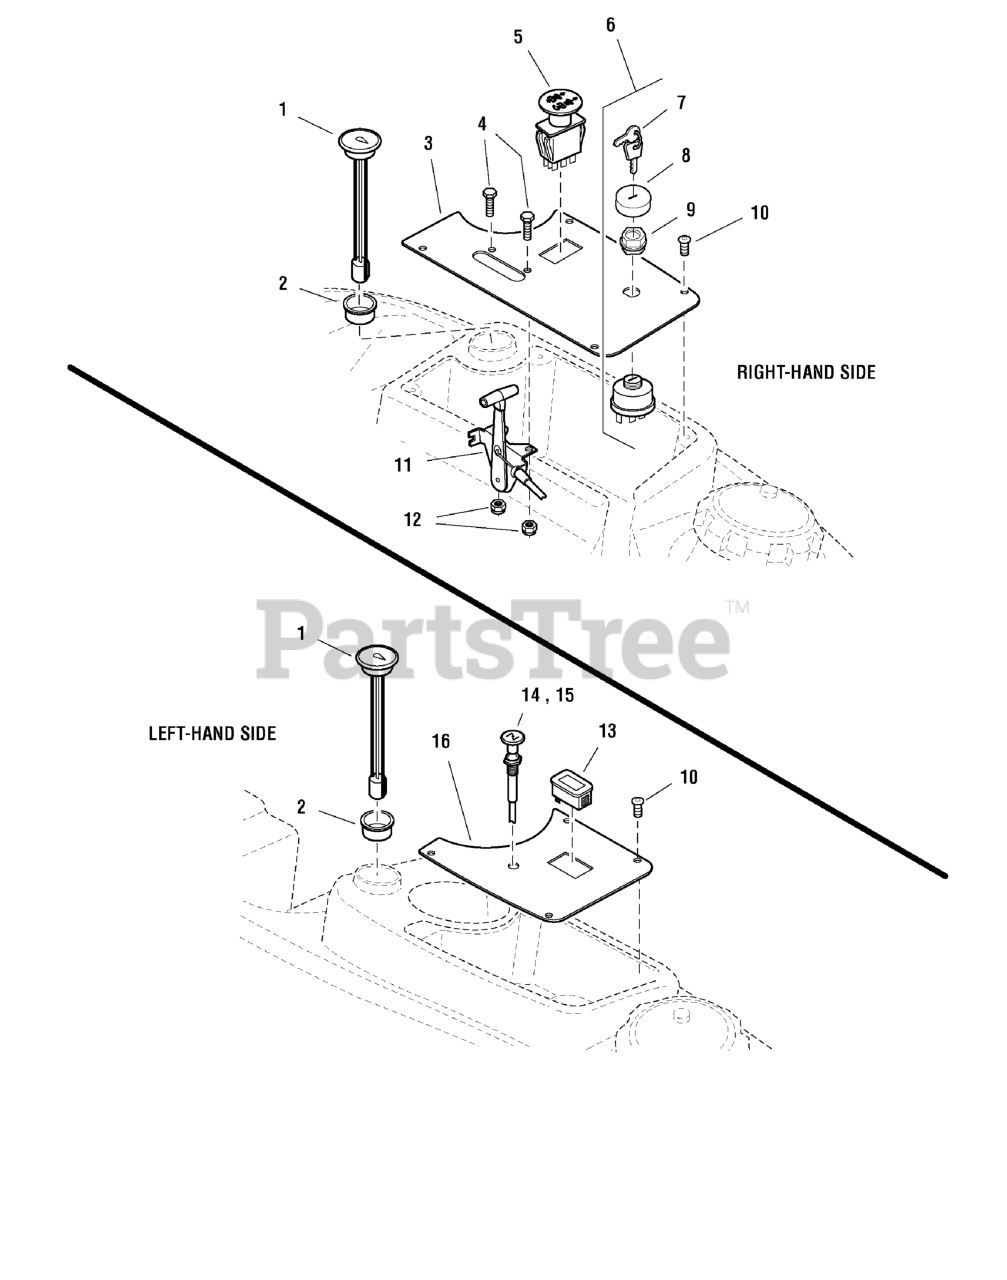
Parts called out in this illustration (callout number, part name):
1	GAUGE, FUEL, 12
2	GROMMET
3	CONTROL PANEL-RH
4	BOLT, 1/4-20 x 3/4
5	SWITCH, BLADE ENGAGEMENT
6	SWITCH, IGNITION, 6 POST
7	KEY, IGNITION MOLDED SET
8	COVER, PLASTIC, SNAP ON
9	PLASTIC NUT
10	SCREW, Allen Head, 1/4-20 x 1/2
11	CABLE, Throttle, 38"
12	NUT, 1/4-20 HEX SERR. FLANGE
13	HOUR METER
14	CABLE, Choke Control, 39-1/2"
15	CABLE, Choke Control, 51"
16	CONTROL PANEL-LH
